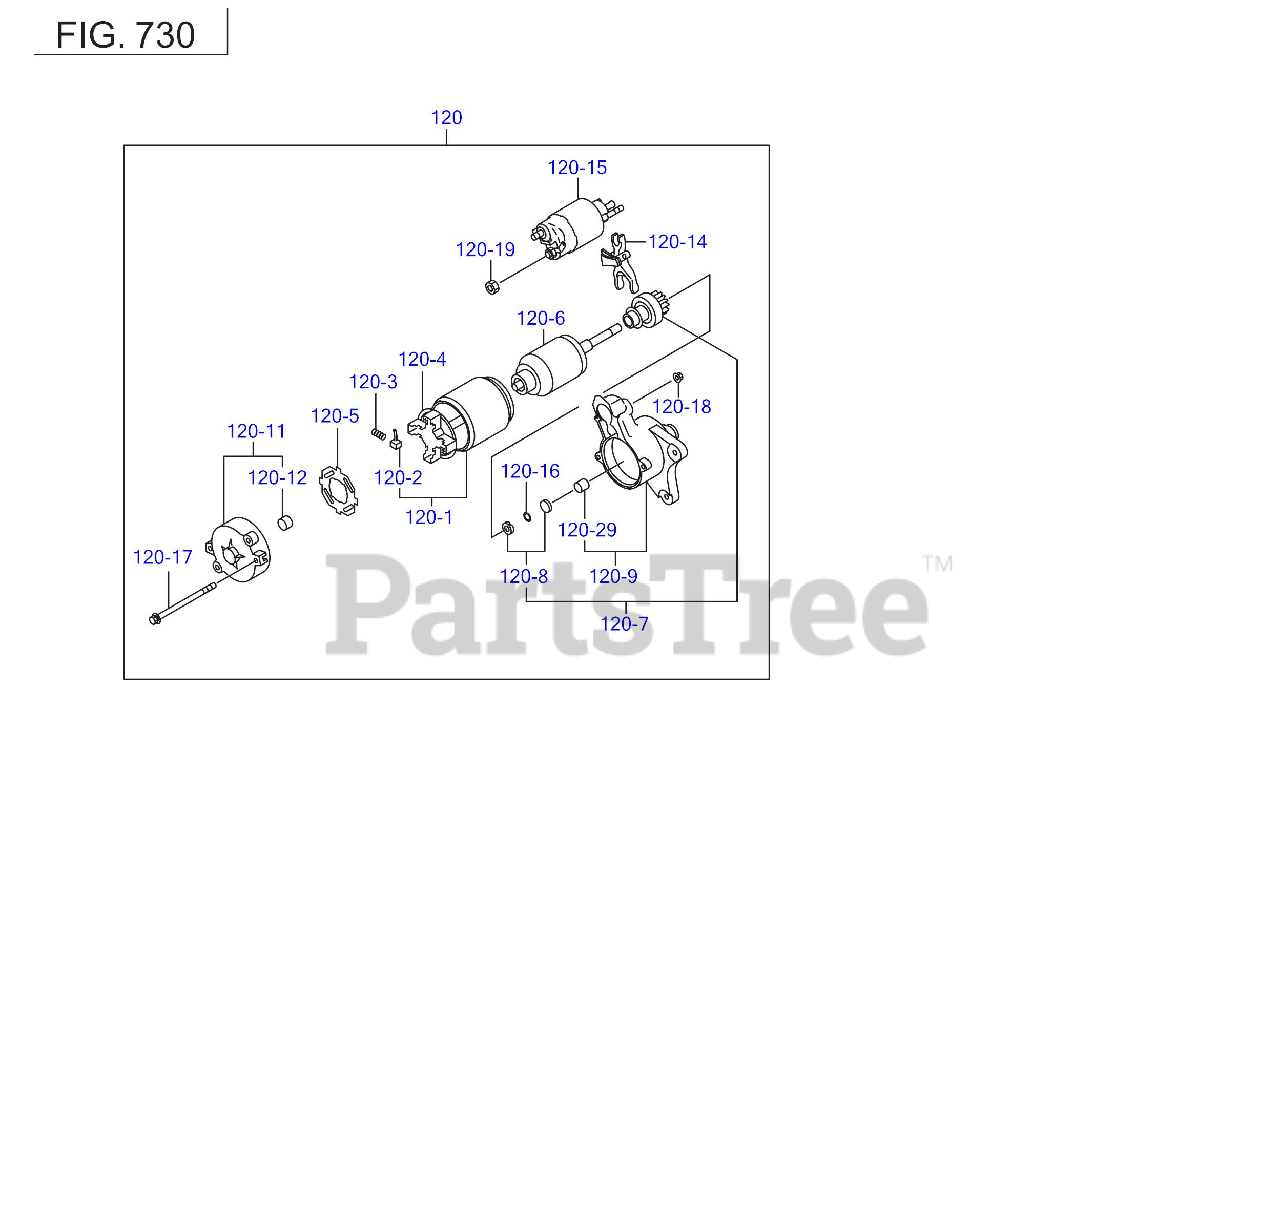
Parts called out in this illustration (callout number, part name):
120	STARTING MOTOR AY
120-1	YOKE CP
120-2	BRUSH
120-3	BRUSH SPRING
120-4	BRUSH HOLDER
120-5	INSULATOR
120-6	ARMATURE AY
120-7	OVER RUNNING CLUT CP
120-8	COLLAR(PINION STOP)
120-9	HOUSING CP
120-11	FRAME CP
120-12	BUSH
120-14	LEVER
120-15	MAGNET SWITCH CP
120-16	SNAP RING
120-17	THROUGH BOLT
120-18	NUT
120-29	BUSH
